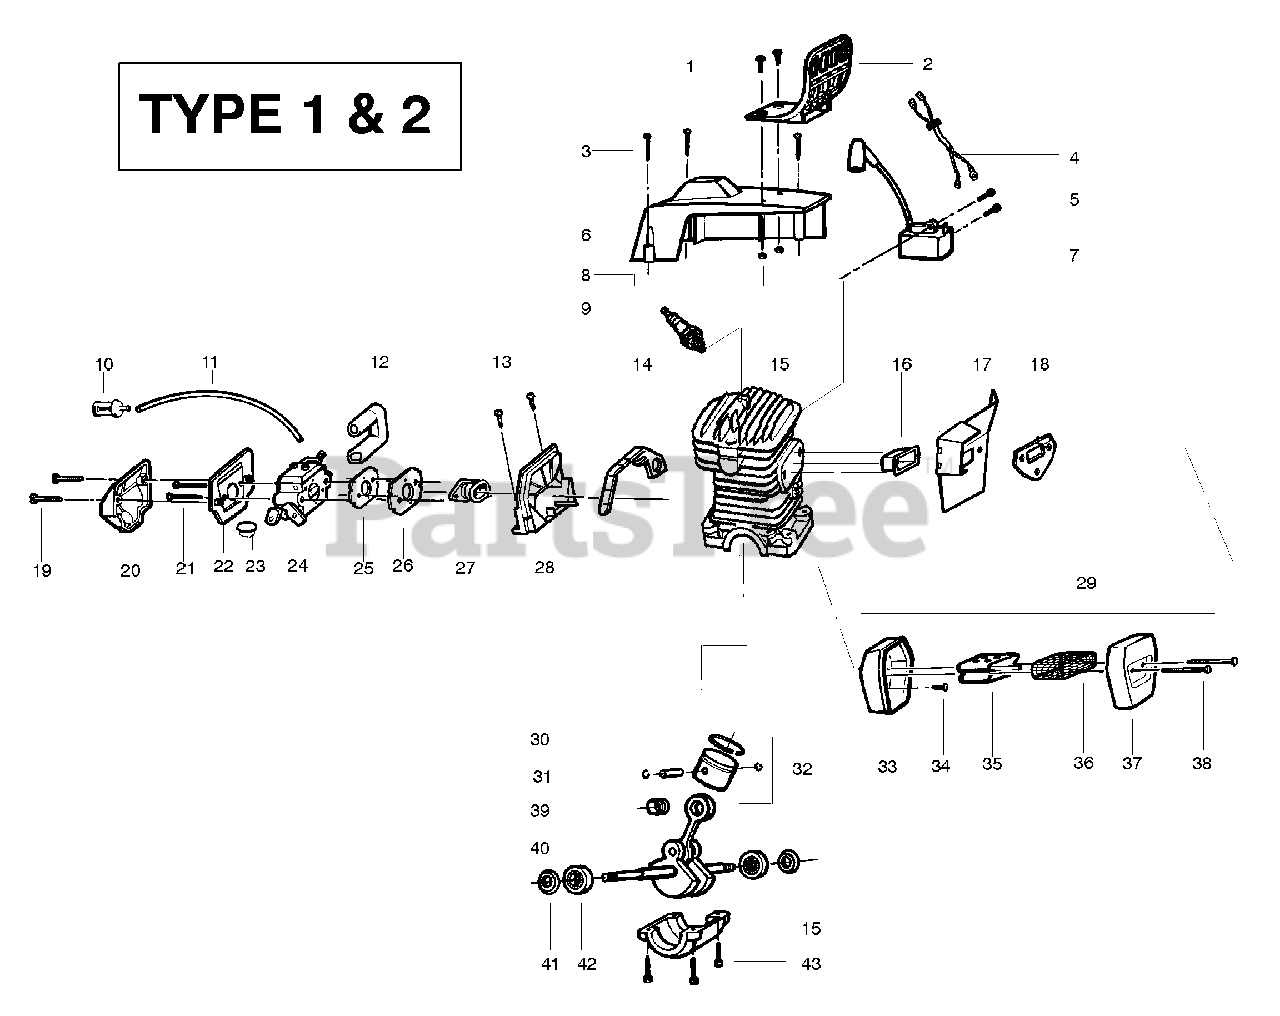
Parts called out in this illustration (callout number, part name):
1	Screw
2	Handguard
4	Assy-Switch Wire
6	Kit-Cylinder Shield
7	Module-Ignition
8	Nut
9	Spark Plug
10	Assy-Fuel Pick-up
11	Kit - Line Carb / Purge
12	Grommet-Carb.
14	Seal-Super Clean
15	Assy-C'case&Cylinder
16	Heat Insulator
17	Muffler Plate
18	Gasket-Muffler
20	Air Filter
22	Filter-Air
23	Isolator
24	Carburetor
25	Gasket-Carburetor
26	Plate-Carburetor
27	Boot-Intake
28	Adaptor-Carb.
29	Kit-Muffler
30	Ring-Piston
31	Retainer-Piston Pin
32	Kit-Piston
33	Muffler Body
35	Diffuser
36	Spark Screen
37	Muffler Cover
38	Muffler Bolt
39	Piston Pin Bearing
40	Assy-C'shaft & Rod
41	C'shaft Seal
42	C'shaft Bearing
